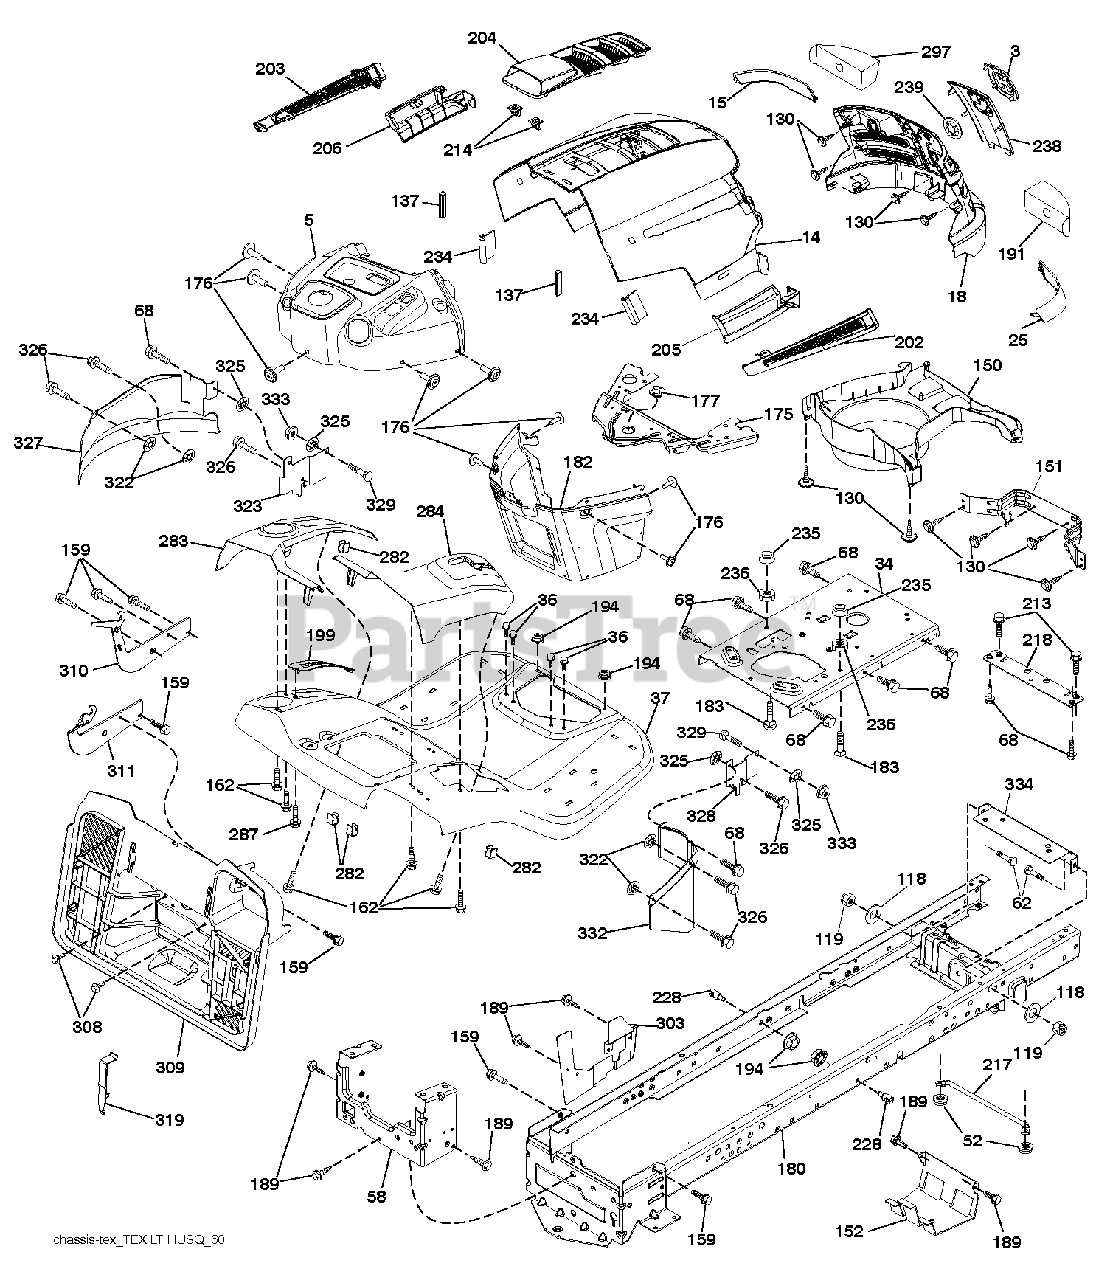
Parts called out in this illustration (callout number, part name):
3	LOGO.HUSQ.GT.LT.CROWN.H
5	SUBASM.DASH.UPPER.W/BUMPER
14	HOOD.HUSQVARNA.LT.ORANGE
15	LENS.HUSQVARNA LT.RH
18	GRILLE.SVC.HUSQVARNA.GREY
25	LENS.HUSQVARNA LT.RH
34	PLATE.ENGINE.10GA.CRD.GENII
36	SCREW 5/16"
52	LOCKNUT
58	DRAWBAR UPPER 2PC SMALL FENDER
62	BOLT D
68	SCREW LT
118	WASHER
130	SCREW.#10 X 0.750.BOS
137	BUMPER DASH
151	BRACKET PIVOT
152	SHIELD.BROWNING.W/TEX
159	SCREW, 3/8-16X3/4
162	SCREW.HI-LO.CONSOLE
175	CROSSMEMBER
176	SCREW.#10-24X5/8.RN.QU
177	BUSHING STEERING
180	CHASSIS.WLDMNT.14GA.2PC.18".TI
182	DASH.LOWER.PREDATOR LT
183	BOLT.5/16-18X1-1/4 FULL THD
189	SCREW
191	INSERT.REFLECTIVE.RH.
194	NUT LOCK HEX FLANGE 5/16-18
199	PLATE DECK LIFT
202	VENT.SIDE.HUSQVARNA.LT.RT
203	VENT.SIDE.HUSQVARNA.LT.LFT
204	SUBASM.TOP.VENT.HUSQ.LT
205	SKIRT.SIDE.HUSQVARNA.LT.RT
206	SKIRT.SIDE.HUSQVARNA.LT.LEFT
213	BOLT
214	CLIP.RETAINER.TINNER.
217	ROD.PIVOT.HOOD
218	X-PIECE.HOOD.STOP.NON/
228	STUD.FASTNER.W/ANTI-ROTATE
234	BUMPER.HOOD.TEX.HUSQVARNA
235	SPACER FENDER
236	NUT.CENTERLOCK.5/16-
238	TRIM.HUSQ LT.668
282	CLIP.RETAINER.CONSOLE.LT.HUSQ
283	CONSL.DECKLIFT.LH.SRD.TEX.CRD
284	CONSL.SHIFT.GEAR.RH.SRD.GREY
287	SCREW 1/4X20
297	INSERT REFLECTIVE
303	SHIELD CHASSIS LEFT
308	BOLT, 5/16-18 X 1 3/4
309	BACKPLATE.BAGGER.V2.SRD
310	LH.ADJUST.HANGER.BRACKET.ASM
311	RH.ADJUST.HANGER.BRACKET.ASM
319	BRACKET.ACTUATOR.BAGGER.SRD
322	PALNUT 1/4
323	GUARD FRONT LEFT
325	WASHER 5/16"
326	SCREW 14-20 X 5/8
327	GUARD LEFT
328	GUARD FRONT RIGHT
329	BOLT
332	GUARD RIGHT
333	NUT.71038.31-18.HEX.NYLOCK
334	BRACKET.ENGINE
